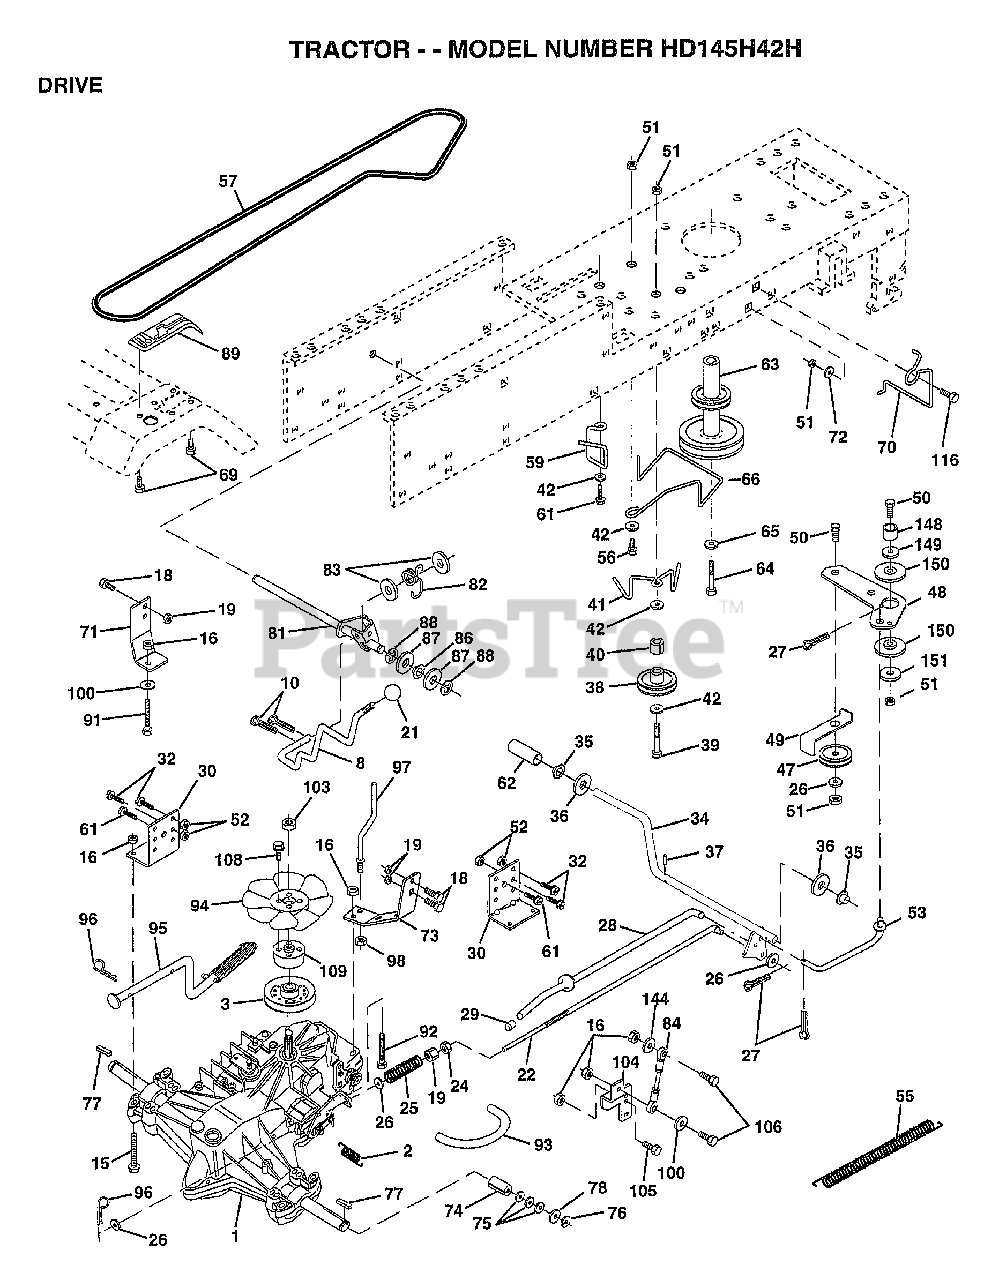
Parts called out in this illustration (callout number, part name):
1	TRANSAXLE HYD 0319-0500
2	SPRING RET BRAKE
3	PULLEY.4.20.HYDRO
8	ROD SHIFT FEND LT
10	PIN COTTER 1/8
15	BOLT.HX.FLG.5/16
16	NUT
18	BOLT
19	NUT
21	KNOB T (1/2-HOLE)
22	ROD.BRAKE.HYDRO.
24	NUT
25	SPRING ROD LT
26	WASHER
27	COTTER PIN
28	ROD.BRAKE.PARK.LT
29	PLUNGER CAP T
30	TRANSAXLE MTG BKT
32	BOLT
34	SHAFT ASM-PEDAL F
35	NYLON BEARING
36	WASHER LT
38	PULLEY.IDLER.FLAT
39	BOLT
40	SPACER T
42	WASHER
48	BELLCRANK.CLUTCH
49	RETAIN BELT
53	"LINK, CLUTCH T"
55	"SPRING, RETURN LT"
59	KEEPER BELT CNTSP
61	SCREW
62	PEDAL COVER T
63	PULLEY.ENGINE
64	BOLT
65	LOCKWASHER
66	ENGINE BELT KEEPR
69	SCREW HEXWSH H-L
70	KEEPER BELT ENG
71	STRAP.TORQ.LH.HYD
72	WASHER
73	STRAP.TORQ.RH.HYD
74	SPACER SPLIT
75	WASHER
76	E-RING LT
77	SQUARE KEY
78	WASHER
81	SHAFT ASSEMBLY
82	"SPRING,TORSION"
83	WASHER
84	ROD.TIE.BALL.HYD.
86	BUSHING
87	WASHER D
88	KLIP RING
92	HEX BOLT
93	"LINE FUEL HYD 4"""
94	"FAN 7"" HYDRO"
96	SPRING. RETAINER 1"
97	KEEPER.BELT.RH.HY
98	NUT
100	WASHER M
104	ARM.CONTROL.PUMP
105	SCREW CAP 5/16-18
106	BOLT
108	SCREW.HXHD.10-20
109	ADAPTOR.FAN.HYDRO
116	BOLT RDHD 3/8-16
144	WASHER
149	SPACER RETAINER
150	BUSHING.NYLON
151	WASHER
